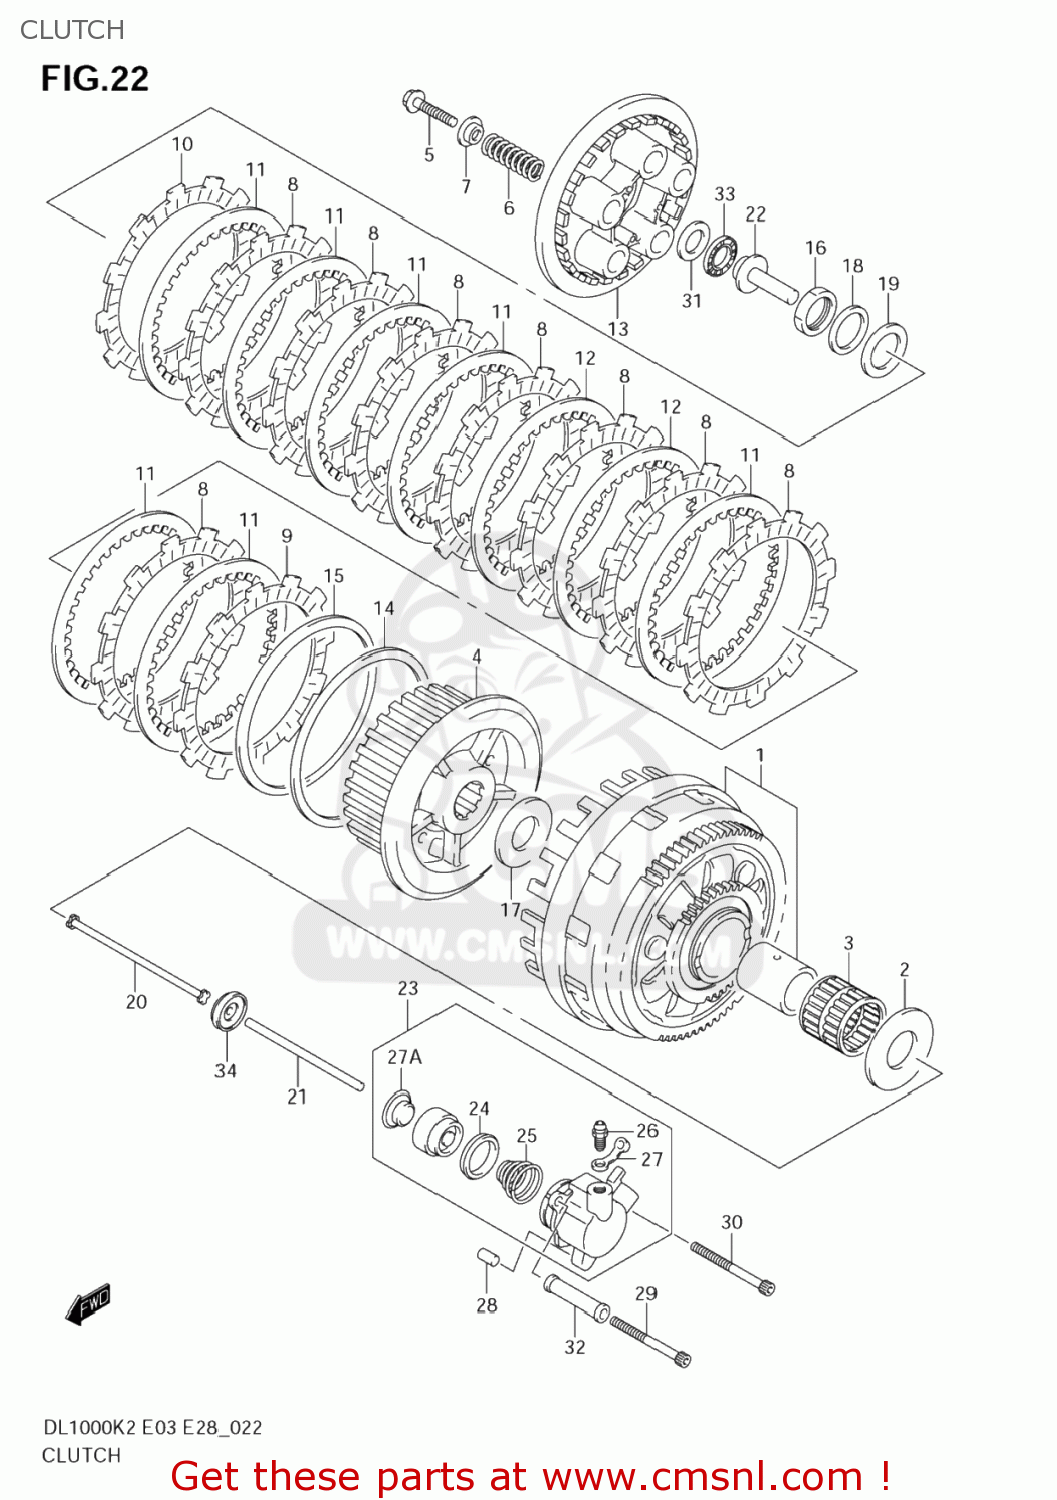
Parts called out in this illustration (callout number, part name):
1	GEAR ASSY,PRIM
2	WASHER(25X52X2.5)
3	BEARING(35X40X39.8)
4	HUB,CLUTCH SLEEVE
5	BOLT,CLUTCH SPRING
6	SPRING,CLUTCH
7	WASHER
8	PLATE,CLUTCH DRIVE NO.1 (NAS)
9	PLATE,CLUTCH DRIVE NO.3 (NAS)
10	PLATE,CLUTCH DRIVE NO.2 (NAS)
11	PLATE,CLUTCH DRIVEN NO.1(T:2.0 (NAS)
12	PLATE,CLUTCH DRIVEN NO.2(T:2.3 (NAS)
13	DISC,CLUTCH PRESSURE
14	SEAT,WAVE WASHER
15	WASHER,CLUTCH PLATE WAVE
16	NUT
17	WASHER(25X50X2.5)
18	WASHER
19	SHIM(25X38X1)
20	ROD,CLUTCH
21	ROD,CLUTCH PUSH,L
22	PIECE,CLUTCH PUSH
23	CYLINDER,CLUTC
24	CUP
25	SPRING,CLUTCH CYLINDER
26	BLEEDER
27	CAP,BLEEDER
27A	COVER,DUST
28	PIN
29	BOLT
30	BOLT
31	WASHER(15.5X28X1)
32	SPACER,CL RLSE CYL
33	BEARING(15X28X2)
34	SEAL,OIL(6X34X10.5)
